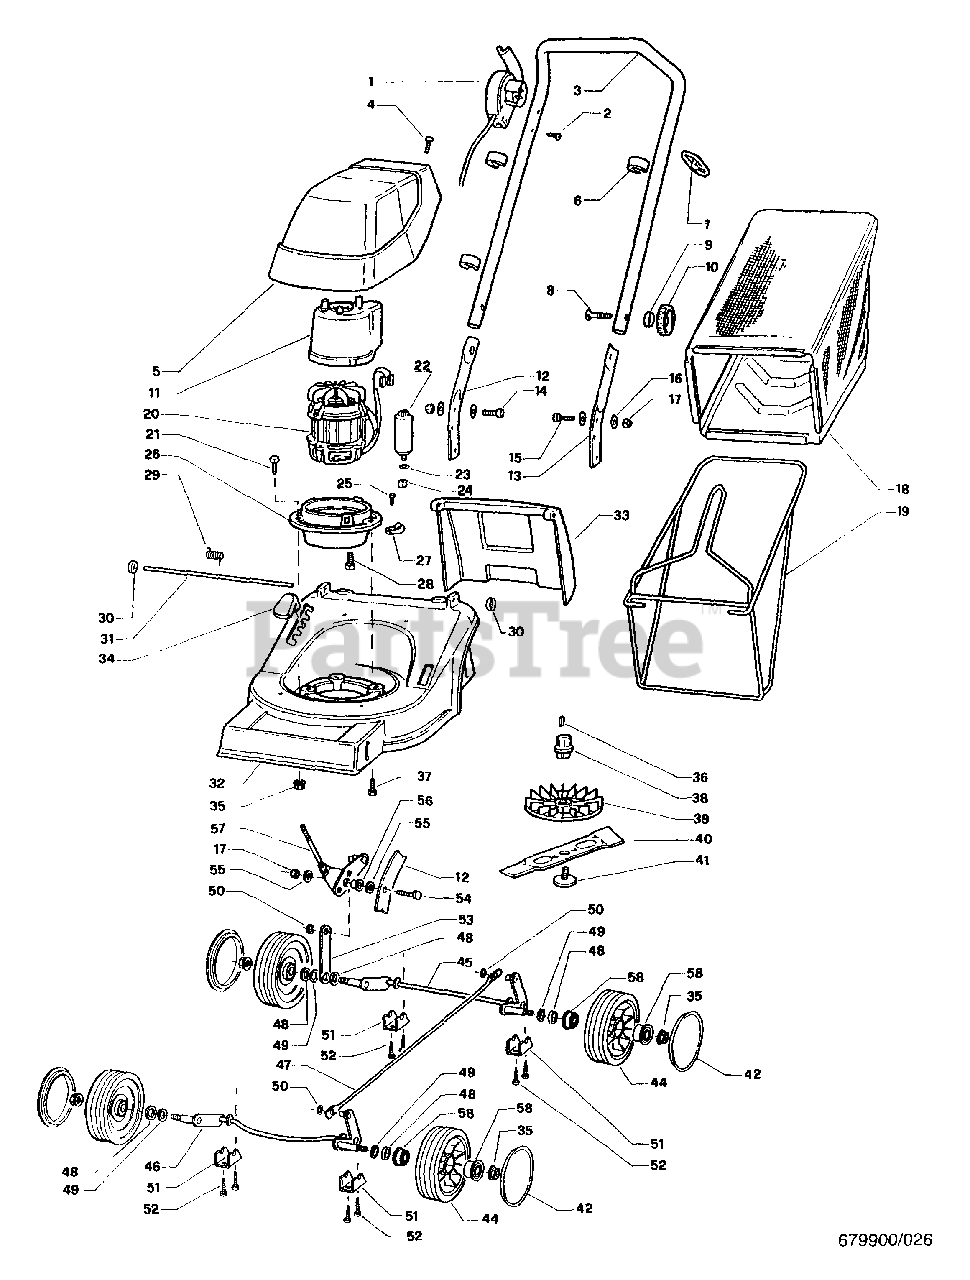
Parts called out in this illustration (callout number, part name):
3	Handle, Upper
7	Retainer, Ext. Cable
11	Housing, Motor
12	Handle, Right Lower
13	Handle, Left Lower
19	Frame, Bag
22	Condensor
26	Flange Housing Motor
39	Fan, Cooling
42	Cover, Wheel
45	Pivot, Rear Axle
46	Pivot, Front Axle
47	Linkbar
51	Bracket
53	Bracket
56	Bushing
58	Bearing
